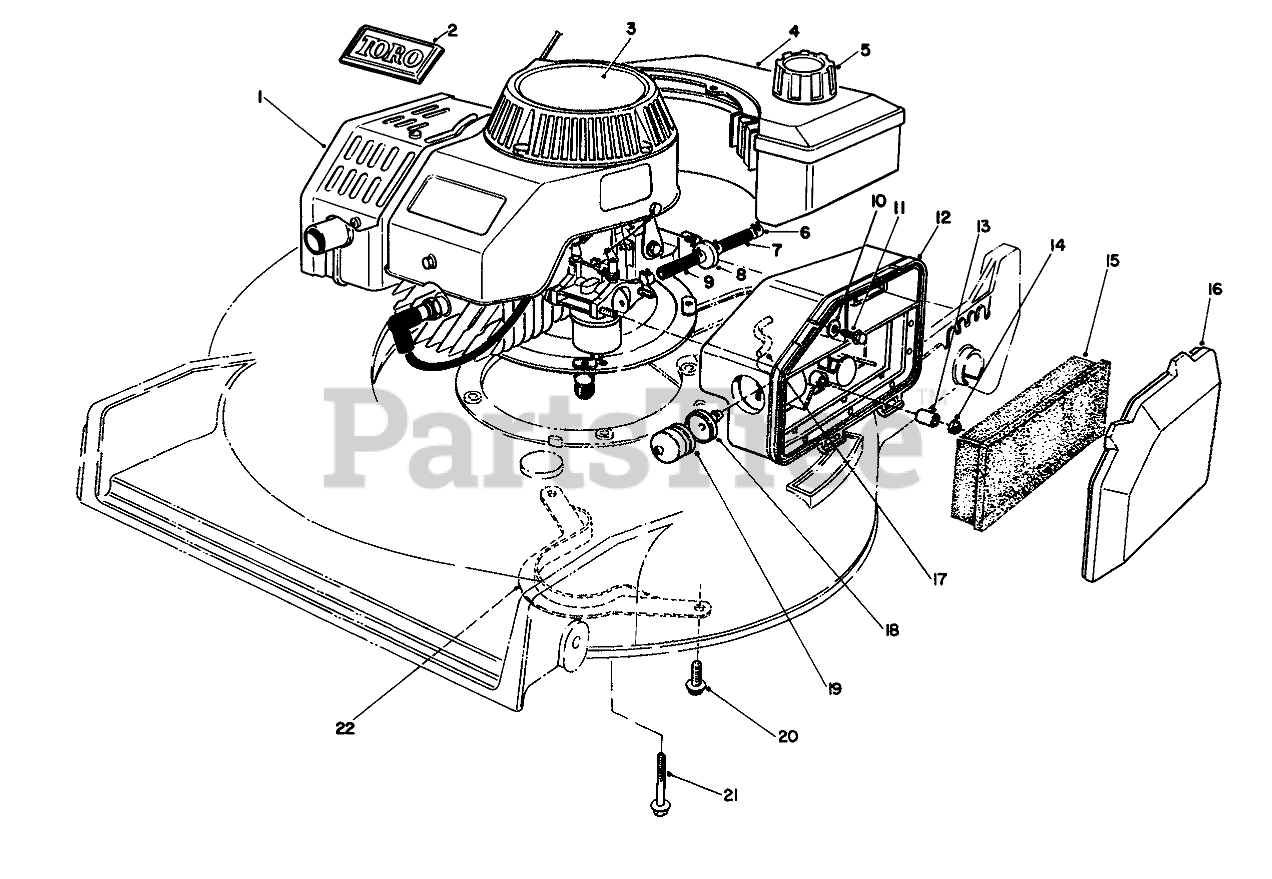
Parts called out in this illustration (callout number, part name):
2	TORO LOGO PLT
3	DECAL- 2 CYC RECOIL
4	Gas Tank Assembly
5	GAS CAP ASM
6	CLAMP-FUEL LINE
7	HOSE-FUEL
8	FILTER-FUEL
9	HOSE-FUEL
10	WASHER-FLAT
11	SCREW-HH
12	BODY-AIR CLEANER
13	SPACER
15	ELEMENT-AIR CLEANER
16	COVER-AIR CLEANER
17	HOSE-PRIMER
18	BODY-PRIMER
19	BULB-PRIMER
20	SCREW-HWHTF
21	SCREW-HHF
22	BBC BELT GUIDE
